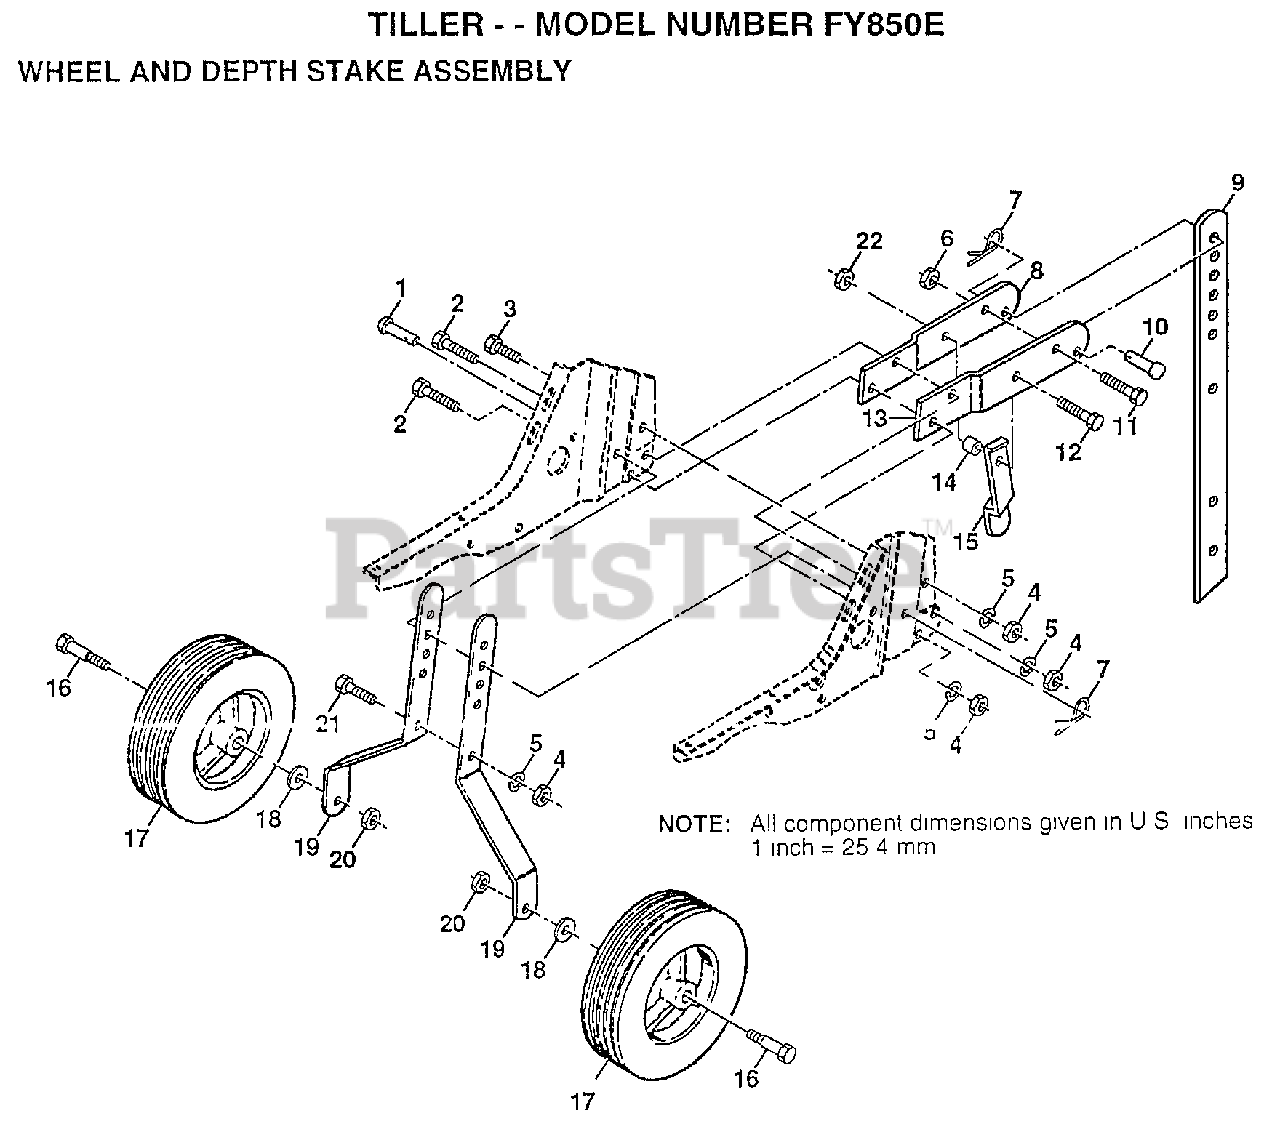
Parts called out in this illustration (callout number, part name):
1	DRILLED RIVET RT
3	BOLT
4	NUT.HEX.5/16-18
5	LOCKWASHER
6	NUT
7	SPRING.RETAINER
11	BOLT
12	BOLT.HEX.5/16-1.5
14	WASHER
15	STAKE SPRING TI
16	BOLT SHOULDER
18	WASHER
22	NUT
